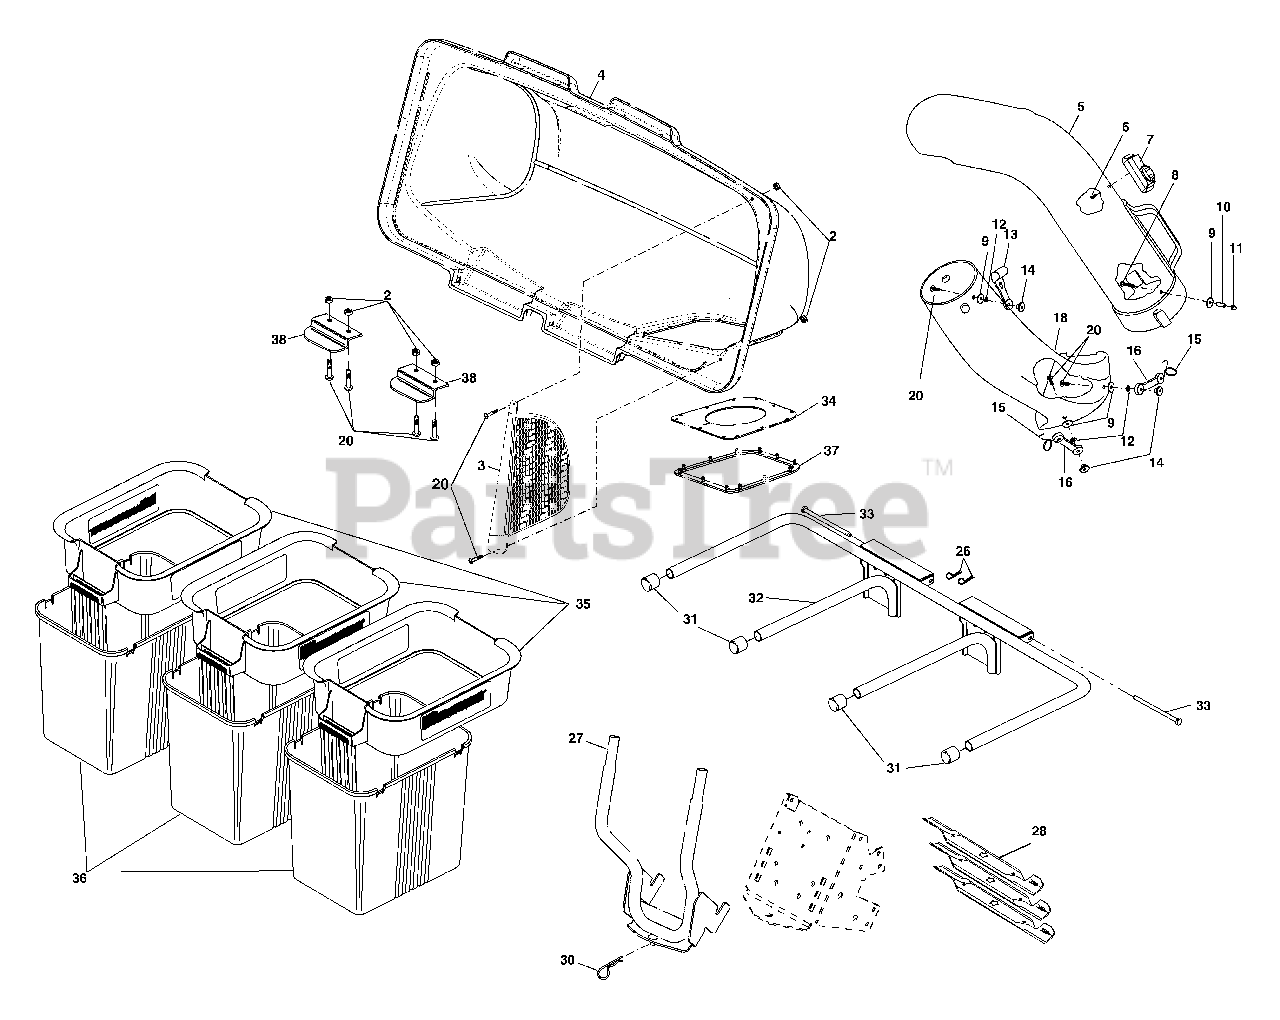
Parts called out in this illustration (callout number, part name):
2	Nut, Crownlock #10-24
3	Screen, Cover
4	Cover Assembly
5	Chute, Upper
6	Screw, Special #10-14x1/2
7	Full Bag Indicator
8	Screw, #10-24 x 1-1/8
9	Washer 3/16x3/4x16 Ga.
10	Spacer, Split
11	Nut, Acorn #10-24
12	Washer, lock
13	Latch, Chute
14	Nut, Weld
15	Latch, Hook
16	Rubber, Latch
18	Chute, Lower
20	Screw #10-24 x 5/8
26	Spring, Retainer
27	Support Assembly "A"
27	Support Assembly "B"
28	Blade, 54" High Lift
30	Spring, Retainer
31	Plug, Tubing End
32	Bagger, Frame
33	Pin, Hinge
34	Gasket, Cover
35	Container, Top
36	Container, Bottom
37	Ring, Cover Gasket
38	Latch Handle, Cover
